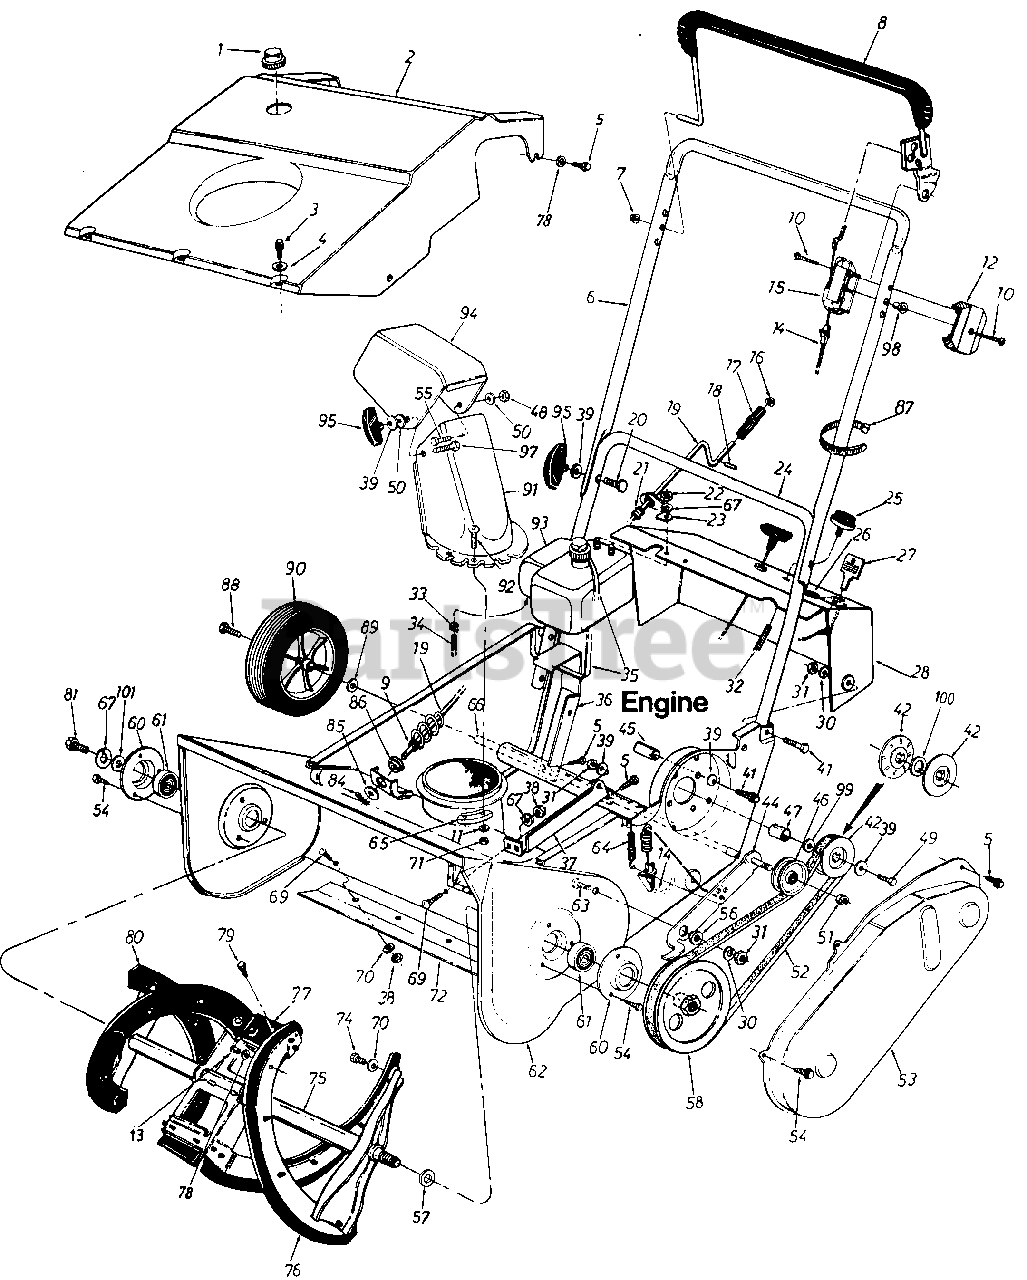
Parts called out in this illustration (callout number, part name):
1	CAP-GAS
2	SHROUD-21IN
3	SCREW-HEX B-TAP #10 X .38
4	WASHER-SPRING
5	SCREW-HEX L-WASH HD
8	HANDLE ASSY-CONTROL-LH
9	WASHER-FL-.385 ID X .62 OD X .063
10	SCREW-TRUSS MACH
11	WASHER-FL-.281 ID X .50 OD X .063
12	PANEL HALF-CONTROL
13	RIVET-POP
14	CABLE-CLUTCH
15	PANEL HALF-CLUTCH
17	KNOB-CHUTE CRANK
18	PIN-ROLL 1/18 DIA
19	CRANK ASSY-CHUTE
20	BOLT-CARRIAGE 5/16-18 X 1.75
21	GROMMET
22	NUT-HEX 1/4-20
23	BRACKET-CHUTE CRANK
24	HANDLE-LOWER PAINTED
25	PRIMER
27	KEY-STARTER-TEC
28	PANEL-DASH
30	WASHER-LOCK-5/16
31	NUT-HEX 5/16-18
32	HOSE-PRIMER
33	CLAMP-HOSE 1/2OD TUBE
34	FUEL LINE-1 UNIT = 1 INCH
35	TIE-CABLE
36	BRACKET-ENGINE SUP
37	SUPPORT-ENGINE
38	NUT-HEX JAM 1/4-20
39	WASHER-BELL .337 X .867 X .057
41	SCREW-HEX 5/16-18 X 1.50
42	PULLEY-HALF-V
44	BRACKET ASSY-IDLER
45	SPACER
46	PULLEY-IDLER
47	SPACER
48	NUT-HEX CENTER L-5/16-18
49	SCREW-HEX 5/16-24 X .75
50	WASHER-FL-.312 X 1.125 X .125
51	NUT-HEX LOCK 3/8-24
52	BELT-V 3/8 X 34.4
54	SCREW-HEX B-TAP 1/4 X .38
55	BOLT-CARRIAGE 5/16-18 X .75
56	SPACER-SHLD
57	WASHER-FL
58	PULLEY-6.0 OD X 3/8
64	SPRING-EXTENSION
65	KEEPER-CHUTE FLANGE
66	AXLE-WHEEL 20.6 IN LG
67	LOCK WASHER 1/4 DIA
69	BOLT-CARRIAGE 1/4-20 X .50
70	WASHER-FL-.28 ID X .74 OD X .063
71	NUT-HEX LOCK 1/4 X 20
72	PLATE-SHAVE
74	SCREW-HEX B-TAP 1/4-.62
76	SPIRAL-RUBBER-LH
77	PADDLE-RUBBER
78	WASHER-FL .192 X .625 X .057
79	SCREW-HEX WASH TAPP
80	SPIRAL-RUBBER-RH
81	SCREW-HEX WASH 1/4-20X.75
84	PIN-COTTER-3/32 DIA X .75
85	WASHER-FL-.406 ID X 1.25 OD
86	BUSHING-HEX
87	TIE-CABLE
88	SCREW-HEX WASH HD 3/8-24 X 7/8
89	WASHER-FL-.510 ID X .75 OD X .033
90	WHEEL ASSY W/TIRE
91	CHUTE-LOWER
92	SCREW-TRUSS MACH
93	TANK-FUEL
94	CHUTE-UPPER
95	KNOB-HANDLE ASSY
97	BOLT-CARRIAGE 5/16-18 X 1.00
98	PIN-CONTROL DISC
99	WASHER-FL-.635 ID X .93 OD
100	WASHER-FL-.640 ID X .94 OD
101	WASHER-FL
